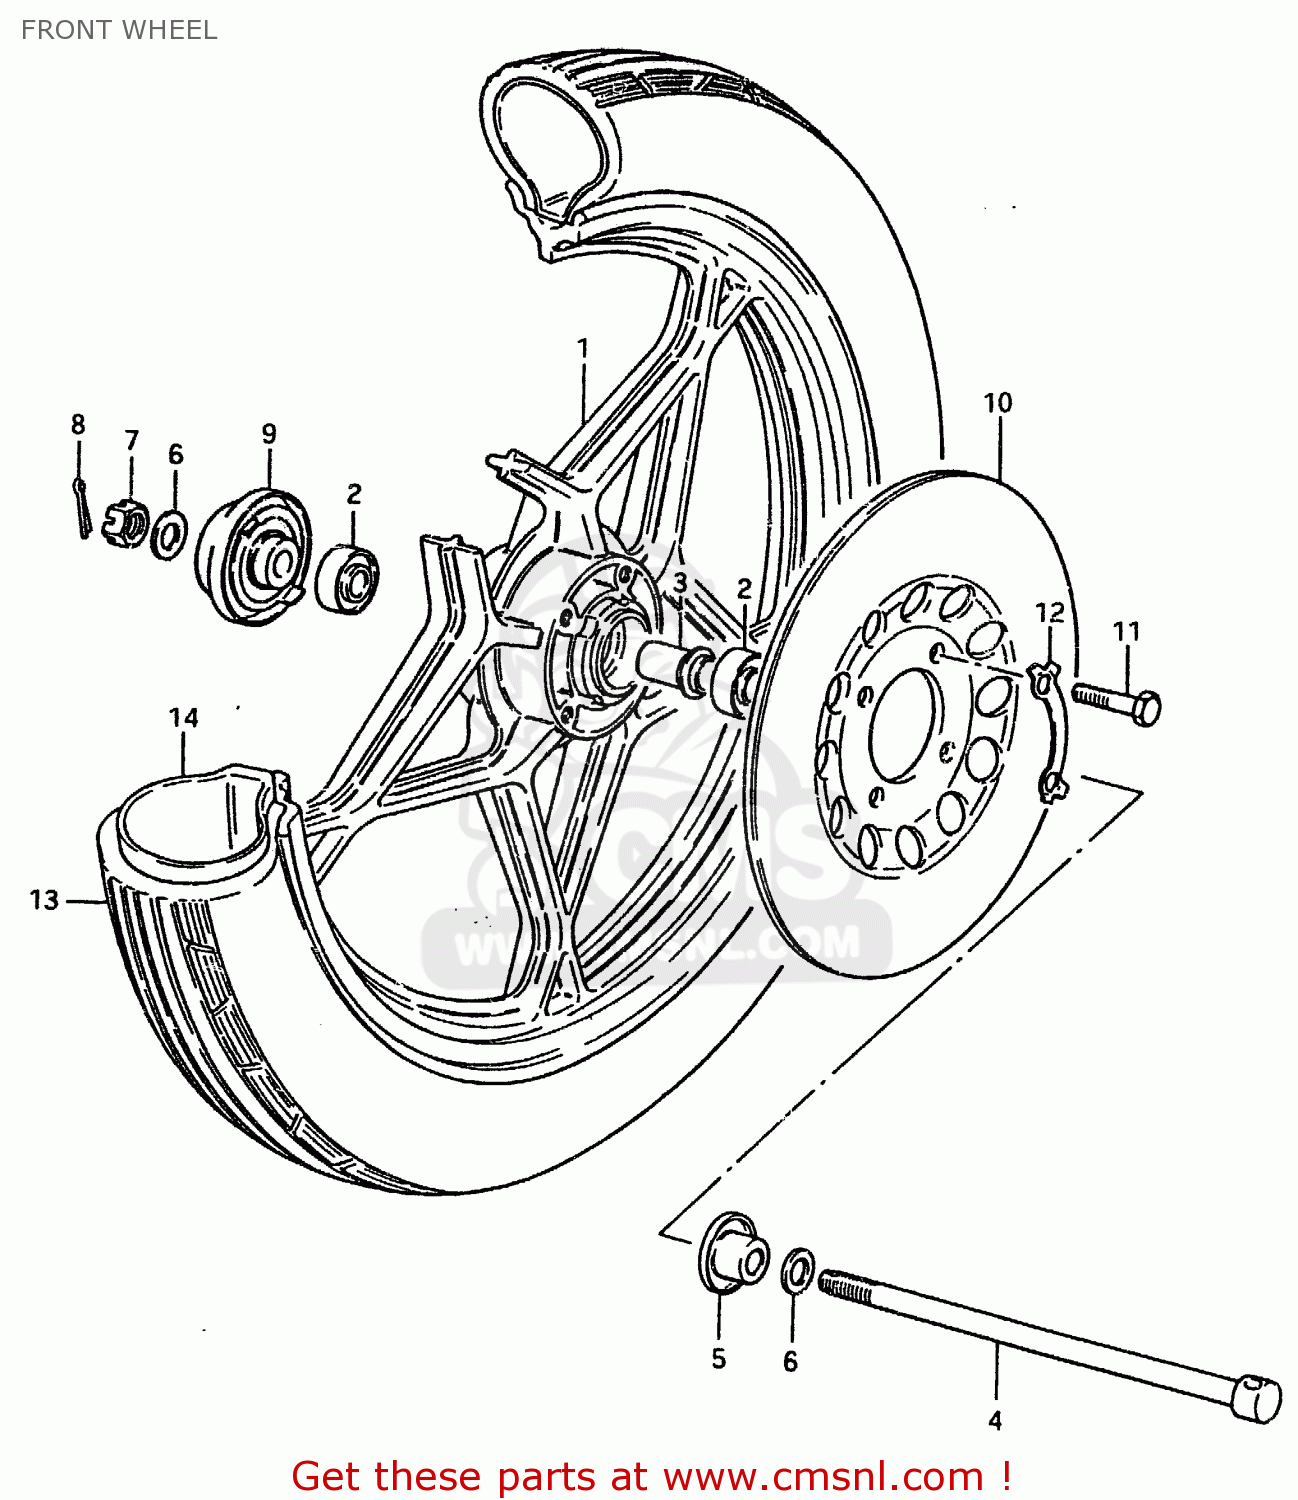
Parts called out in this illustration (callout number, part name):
1	WHEEL, FRONT (J18X1.140 DOT)
2	BEARING
3	SPACER
4	AXLE,FRONT
5	SPACER,FR AXLE,L
6	WASHER(10.5X22X2.3)
7	NUT
8	PIN 20X20
9	BOX, SPPEDOMETER GEAR
10	DISC,BRAKE
11	BOLT(8X30)
12	WASHER
13	TIRE,FR(2.50-18 40L NF2)
14	TUBE,INNER
